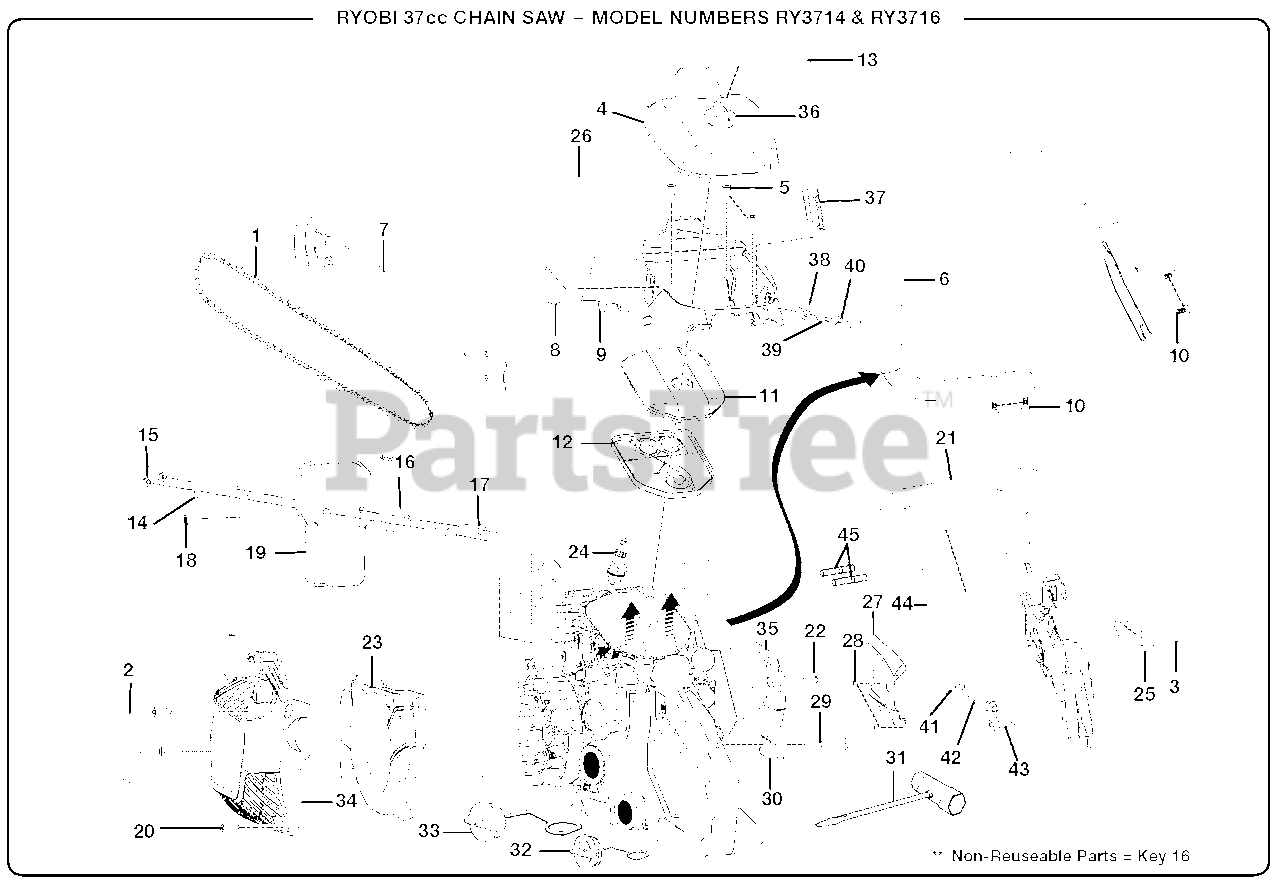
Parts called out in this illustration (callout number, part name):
1	14 in. Chain (RY3714, 52 Drive Link)
1	16 in. Chain (RY3716, 56 Drive Link)
2	Recoil Housing Label (RY3714)
2	Recoil Housing Label (RY3716)
3	Clutch Cover Label
4	Air Cleaner Cover
5	Screw (M5 x 19 mm, T25 Torx Hd.)
6	Front Handle
7	14 in. Guide Bar Assembly (RY3714)
7	16 in. Guide Bar Assembly (RY3716)
8	Grommet (Idle Adjust)
9	Cylinder Cover
10	Screw (M5 x 27 mm, T25 Torx Hd.)
11	Air Cleaner (Upper)
12	Air Cleaner (Lower)
13	Starting Label (RY3714)
13	Starting Label (RY3716)
14	Muffler Bracket
15	Nut (Muffler)
16	Gasket (Muffler)
17	Bolt (Muffler, M5 x 62 mm)
18	Screw (M5 x 14 mm, T25 Torx Hd.)
19	Muffler
20	Screw (10-14 x 22 mm, T25 Torx Truss Hd.)
21	Clutch Cover Assembly
22	Screw (M4 x 10 mm, T20 Torx Hd.)
24	Spark Plug (Bosch WSR6F)
24	Spark Plug (Torch L7RTC)
25	Flange Nut (5/16-18)
26	Warning Label
27	Outer Guide Plate
28	Screw (M4 x 12mm, T20 Torx Hd.)
29	Screw (M5 x 33 mm, T25 Torx Hd.)
30	Chain Guide
31	Combination Wrench
32	Oil Cap Assembly
33	Fuel Cap Assembly
34	Starter Housing Assembly
35	Inner Guide Plate
36	Knob Cover
37	Cylinder Cap
38	Choke Rod Grommet
39	Pin
40	Choke Rod
41	Adjusting Nut
42	Adjusting Screw
43	Adjusting Gear
44	Chain Brake Label
45	Bar Stud (5/16-18 x 23.5 mm / 5/16-18 x 18 mm)
